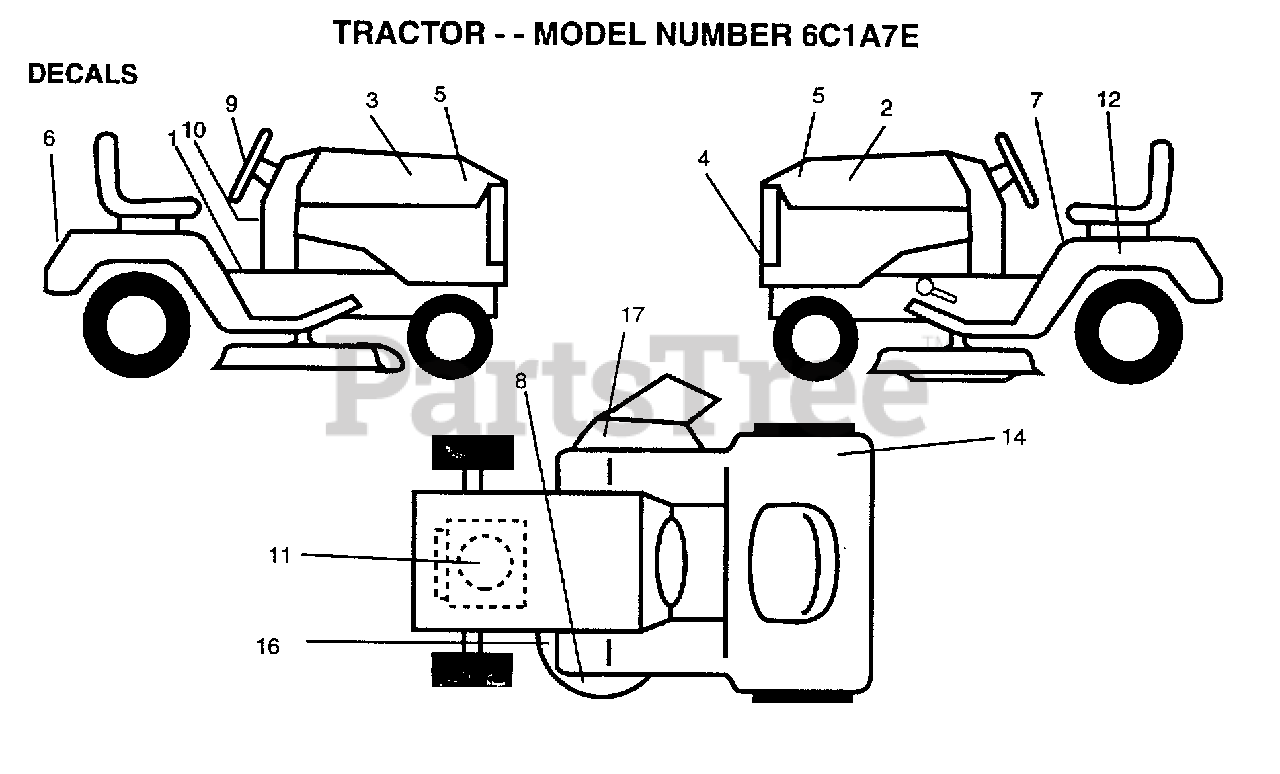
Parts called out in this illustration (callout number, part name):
1	DECAL.OP.INST.SYM
2	DECAL HD RLY LH
3	DECAL HD RLY RH
4	GRILL DECAL
5	DECAL.HOOD.INSERT
6	FENDER DECAL
7	DECAL.READ.O.MANU
9	"DECAL,STR WHL"
10	DECAL.EURO.ST.CE.
11	DECAL, HP, ENGINE
12	DECAL.BTRY.DANGER
16	DECAL.DANGER.CUTF
17	DECAL.V.BELT
